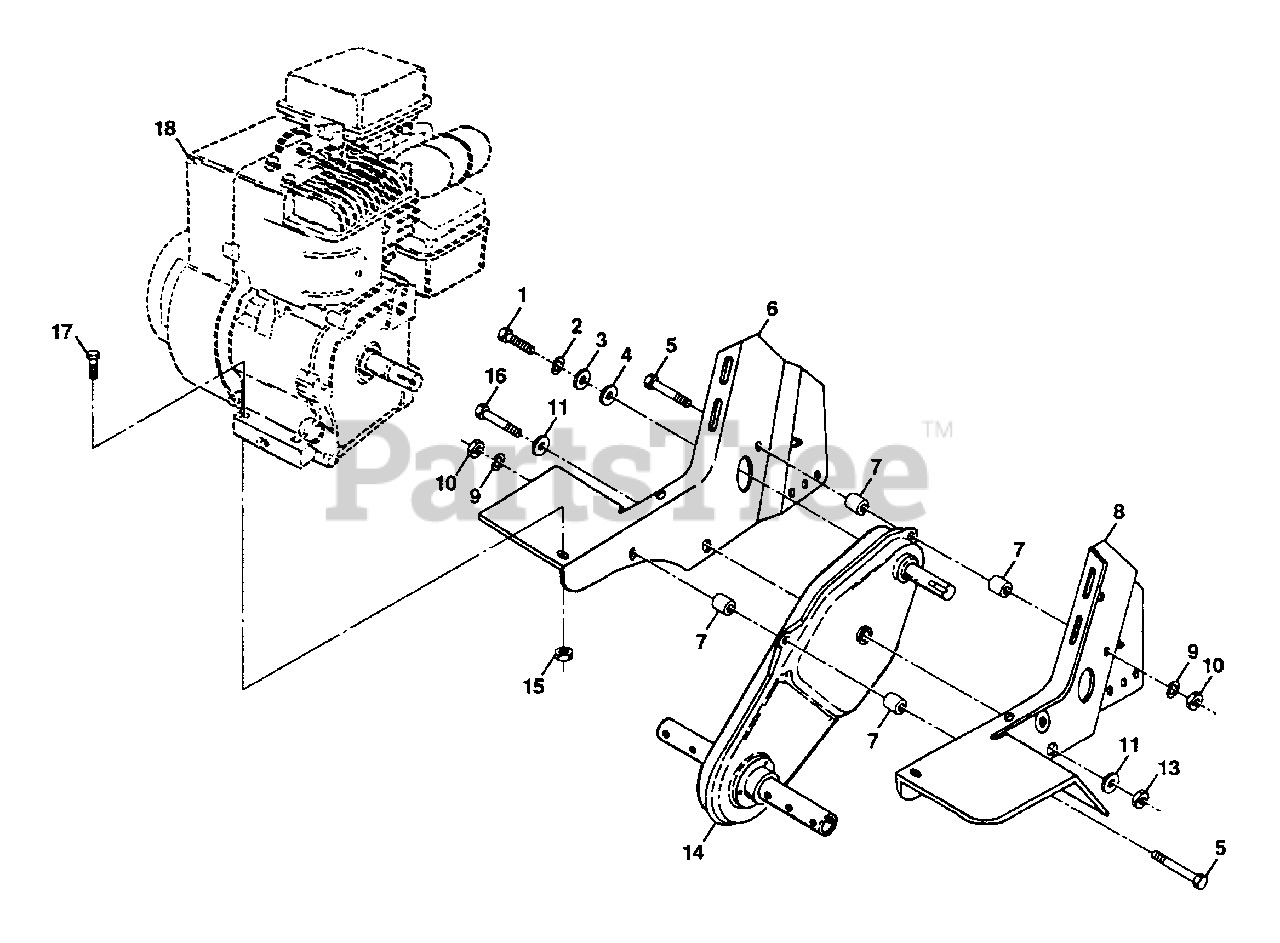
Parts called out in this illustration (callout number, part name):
1	Bolt, Hex 1/4-28 x 3/4 Gr. 5 (AYP part number)
2	Washer, Lock 1/4 (AYP part number)
3	Washer 9/32 x 1-1/4 x 16 Ga. (AYP part number)
4	Washer 9/32 x 7/8 x 12 Ga. (AYP part number)
5	Bolt, Hex 5/16-18 x 2-3/4 (AYP part number)
6	Bracket, Engine, R.H. (AYP part number)
7	Spacer, Split (AYP part number)
8	Bracket, Engine, L.H. (AYP part number)
9	Washer, Lock 5/16 (AYP part number)
10	Nut, Hex 5/16-18 (AYP part number)
11	Washer 13/32 x 13/16 x 11 Ga. (AYP part number)
13	Locknut, w/Insert 3/8-16 (AYP part number)
14	Transmission (AYP part number)
15	Nut, Keps 5/16-18 (AYP part number)
16	Bolt, Hex 3/8-16 x 3-1/4 (AYP part number)
17	Bolt, Hex 5/16-18 x 1-1/2 (AYP part number)
